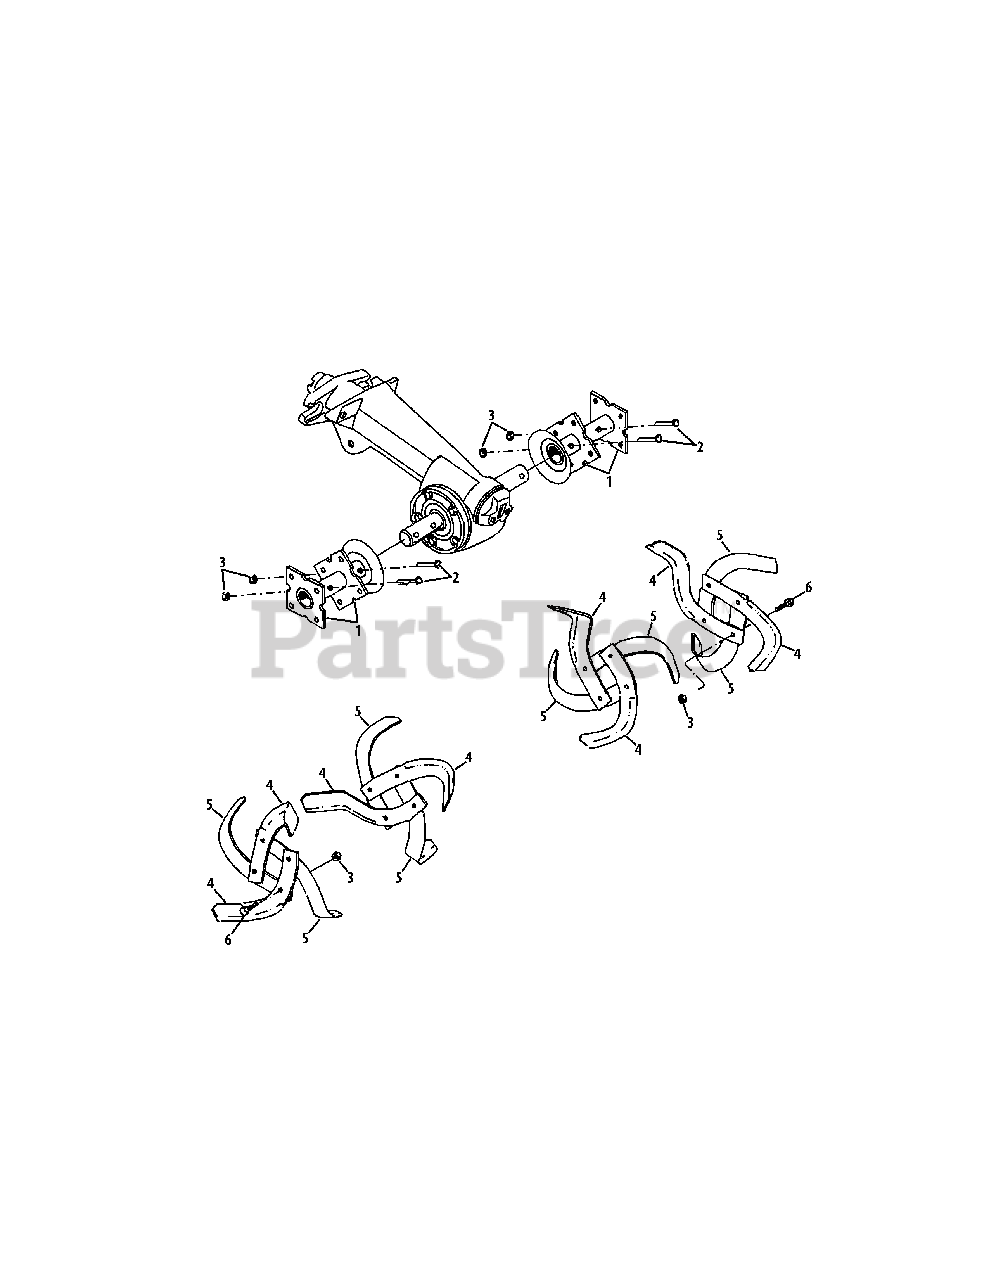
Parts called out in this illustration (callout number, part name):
2	Hex Bolt, 3/8"-16 x 2"
3	Hex Locknut, 3/8"-16
4	Bolo Tine Left
5	Bolo Tine Right
6	Hex Head Screw, 3/8"-16 x 1"
